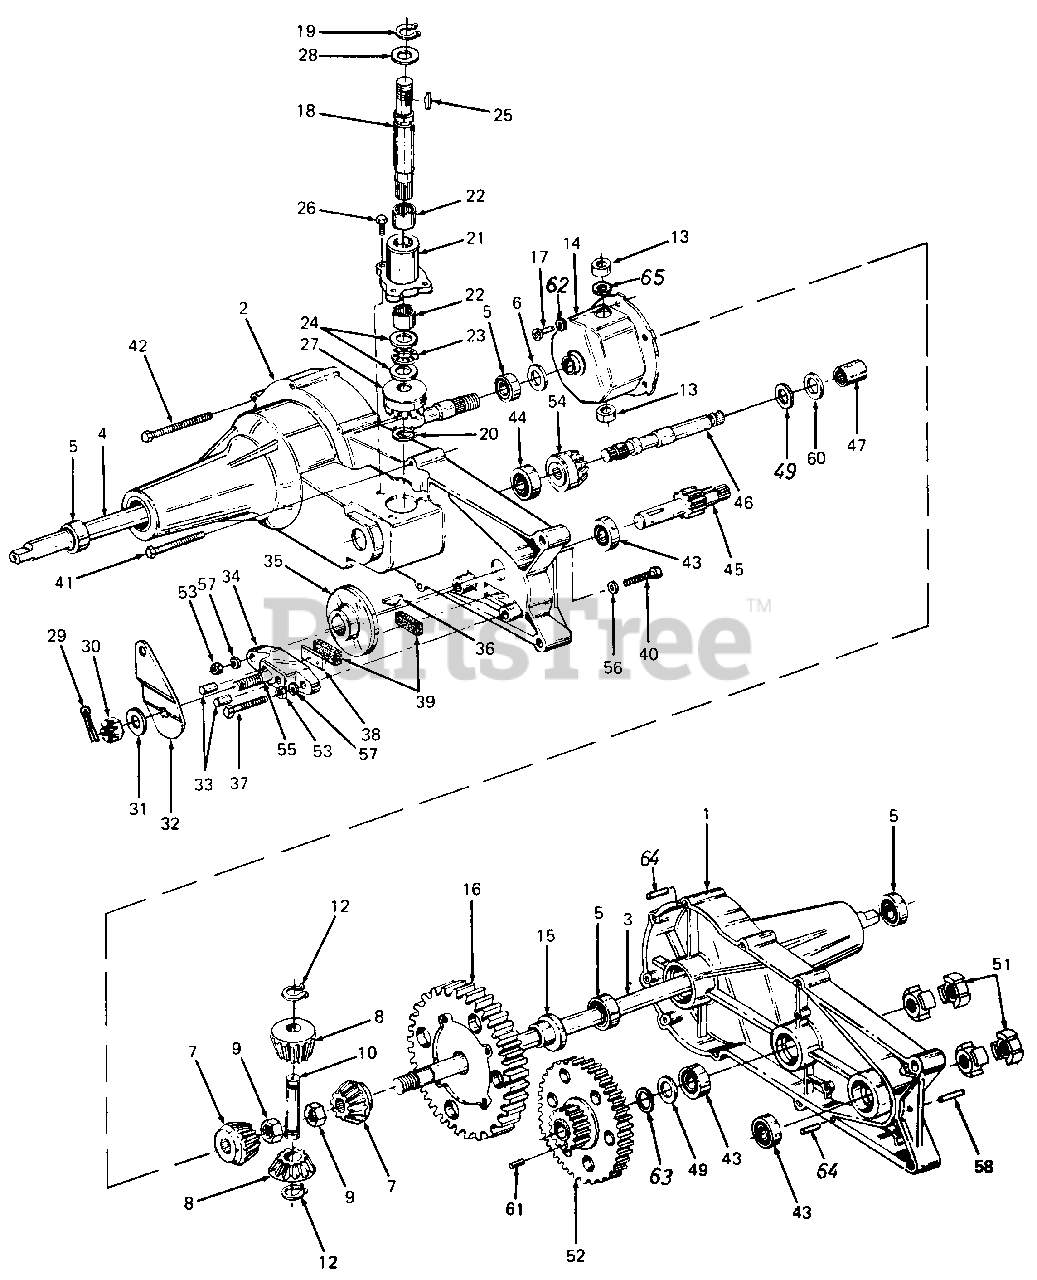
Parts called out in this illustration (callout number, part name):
1	Housing Half, L.H.
2	Housing Half, R.H.
5	Bearing, Ball
6	Washer, Flat, .76 x 1-1/8 x 306 Thk Hdn.
7	Gear Miter
9	Nut, Hex Jam Patch Lock, 1/2-20 0
10	Shaft. Cross
12	Ring, Snap
13	Bearing, Thrust
14	Housing Ass'y. Differential
15	Bearing, Flange, .75 I.D. x .587
16	Gear, Differential, 72 Tooth
17	Bolt ,Torx Head 1/4-28 1 x 5/8" Lg.
18	Shaft, Input
19	Ring, Snap
20	Ring, Retaining, Ext. 7/16 Dia.
21	Bearing, Input Housing
22	Bearing, Needle, 5/8 I.D. x .50 Lg.
23	Bearing, Thrust
24	Washer, Flat, 5/8 I.D. x 1.12 O.D. x .030 Thk.
25	Key #4 Hi-Pro, 3/32 x 5/8 Dia. (Hdn.
26	Screw, Hex Patch Lock, 1/4-20 x 3/4 Lg.
27	Gear, Input Pinion, 17 Tooth
28	Washer, Flat, .62 I.D. x 1.0 O.D. x .030 Thk.
30	Nut, Castle, 5/16-24
31	Washer, Flat, .343 x .88 x .062 0 Thk.
32	Arm, Brake Actuator
33	Pin, Actuating, 5/16 Dia.
36	Key, Hi-Pro, 3/16 x 5/8 Dia.
37	Screw, Hex Patch Lock, 1/4-20 x 1.5 Lg.
38	Plate, Puck
39	Puck, Brake
40	Screw, Hex Cap, 1/4-20 x 1.5 Lg.
41	Screw Hex Self-Tap, 1/4-20 x 2.0" Lg.
42	Screw, Hex Self-Tap, 1/4-20 x 2.75 Lg.
43	Bearing, Ball
44	Bearing, Ball
45	Shaft, Pinion w/11 Tooth Gear
46	Shaft, Drive
47	Bearing, Needle
49	Washer, Flat, 5/8 x 1.12 x .060 Thk.
51	Coupling
52	Gear, Tooth 60 & 17
53	Nut, Hex Jam, 1/4-20
54	Gear, Drive Pinion, 17 Tooth
55	Bolt, Square Hd. 5/16-24
56	Washer, Flat, .265 x .938 x .12 Thk.
57	Washer, Lock, 1/4
58	Pin, Roll, 3/16 Dia. x .50 Lg.
60	Bronze Thrust Brg. 5/8" I.D.
61	Dowel Pin 8/32" x 1/4"
62	Washer,HD. Spring Lock 1/4"
63	Seal, Grease
64	Pin Roll 3/16 Dia.
65	Washer, Flat .62" I.D. x 1.0" O.D. x .20" Thk.
